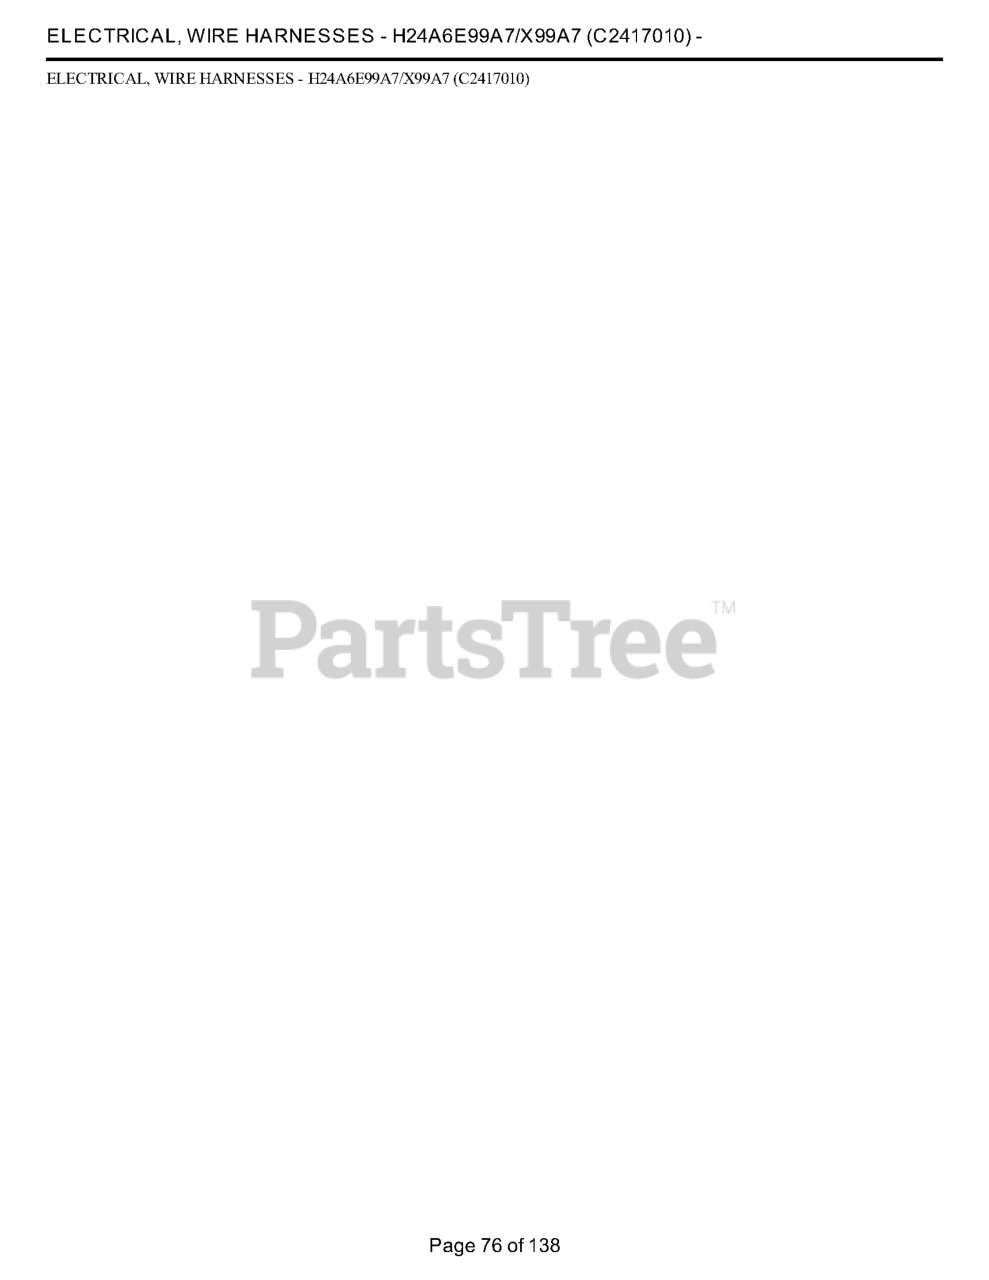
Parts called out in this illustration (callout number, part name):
1	HARNESS-MAIN,GAS,CREW
3	DECAL-RELAY/FUSE BLOCK- GAS
4	TIE-CABLE,25MM STAND OFF
6	CLIP-FIR TREE,9.7-10.0MM HOLE
7	CLIP-OFFSET,FT6 FIR TREE
8	CLIP-EDGE, 1-3mm THICKNESS
9	CLIP-EDGE, 1-3mm THICKNESS
10	CLIP-EDGE,1-3MM THICKNESS
11	CABLE TIE
12	CLIP-ROUTING
13	GROMMET - 65MM, W/FLANGE, BLK
14	ALARM-BRAKE, WARNING
15	RELAY - SSR 10A
16	CAP EVAP CONNECTOR
17	RELAY-SPST-SERIES 303-SEALED
18	COVER-DIAGNOSTIC-W/CLIP
19	FUSE-5A-MINI BLADE
20	BOOT, CIRCUIT BREAKER, RED
21	FUSE- 20 AMP- PARK
22	FUSE-IGN.10 AMP-(10)
23	FUSE-MAIN-30 AMP-(10)
24	BREAKER-CIRCUIT-20 AMP-SEALED
25	FUSE-MINI BLADE-15 AMP
